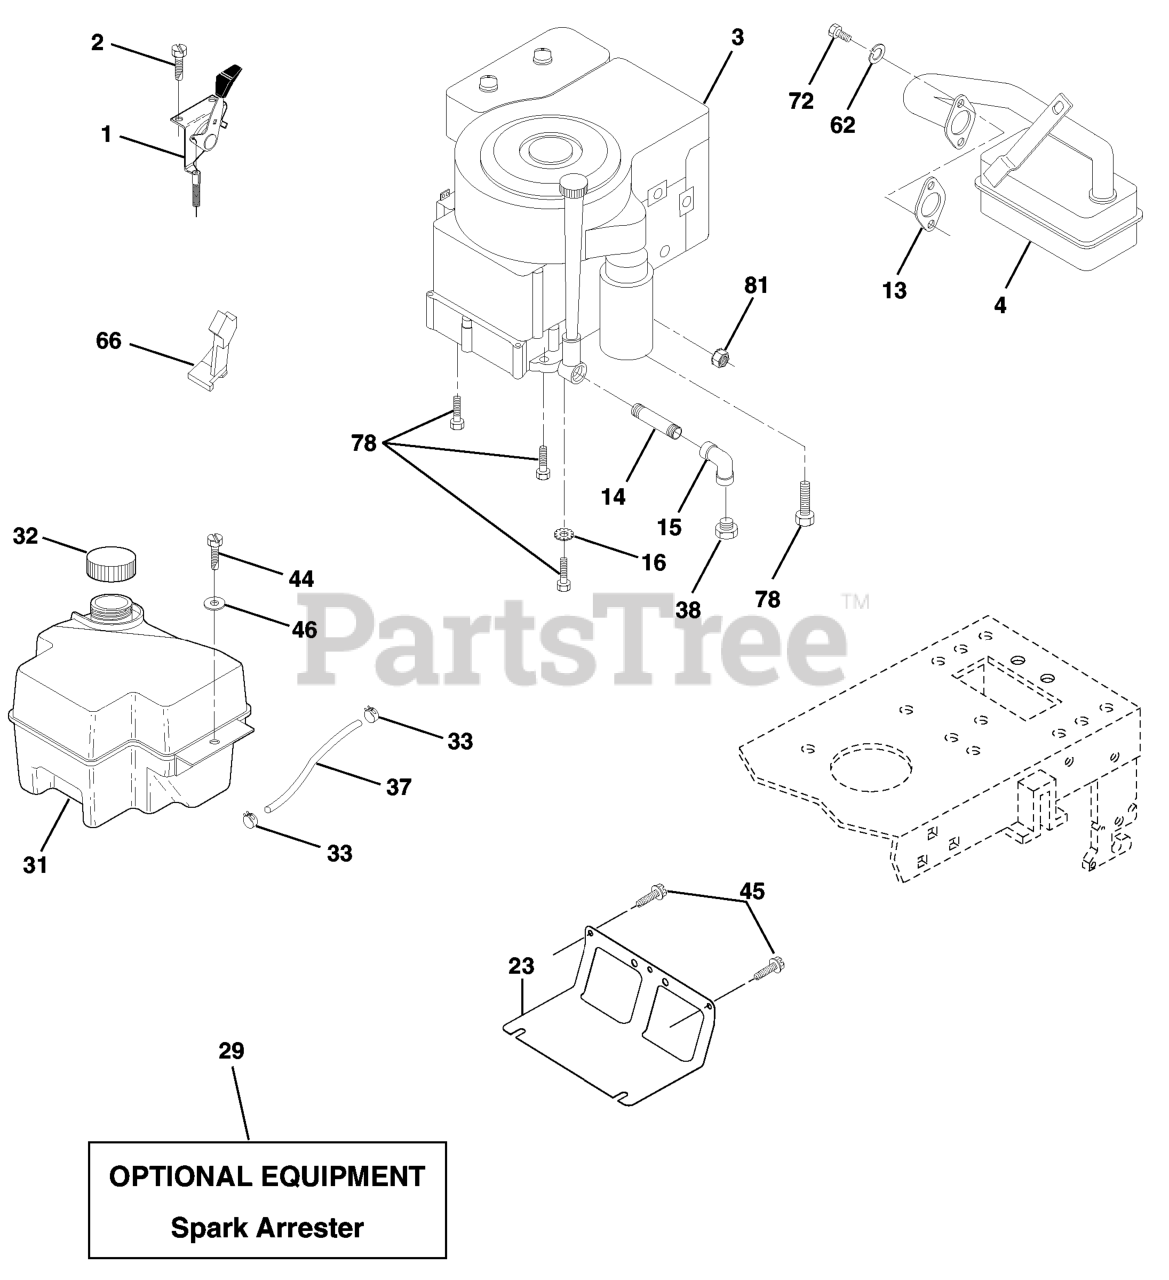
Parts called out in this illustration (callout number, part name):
1	CONTROL
2	SCREW LT
4	MUFFLER.SINGLE.B&S.10-12HP
13	REPL BY 532 27 22-93
14	Nipple Pipe 3/8 Npt X 3"
15	ELBOW
16	LOCKWASHER
23	SHIELD.BROWNING.DBR.GUARD
29	KIT.SPARK ARRESTOR 794945 B&S
31	FUEL TANK
32	FUEL CAP
33	HOSE CLAMP
37	LINE.FUEL.20
38	Plug Oil Drain
44	SCREW HEXWSHR 1/4-20X3/4
45	SCREW, 3/8-16X3/4
46	WASHER
62	WASHER.LOCK.HVY.HLCL.SPR.5/16
66	STOP THROTTLE
72	SCREW
78	SCREW.3/8-16
81	NUT
